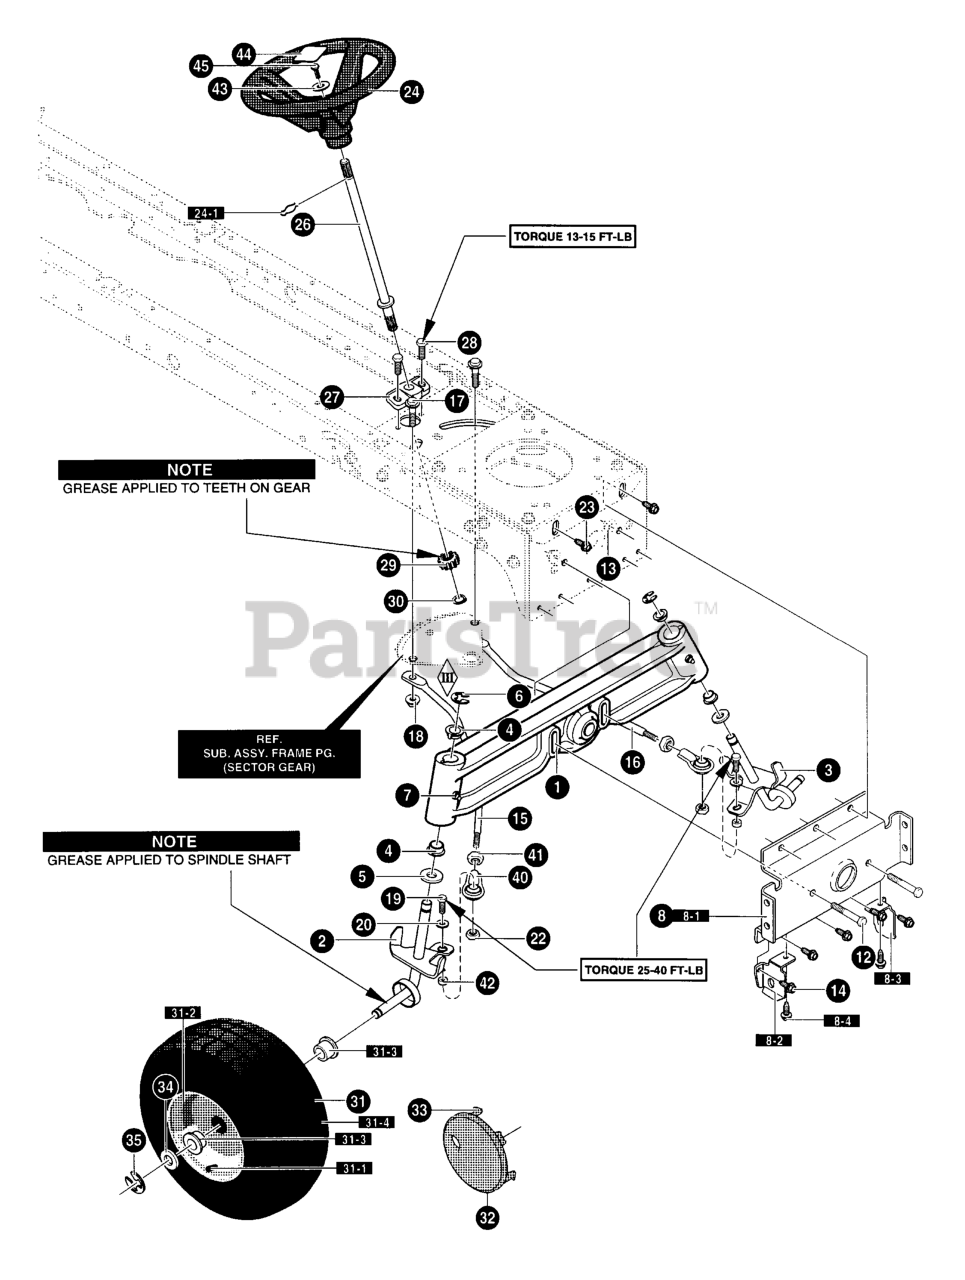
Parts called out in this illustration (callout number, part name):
1	AXLE, FRONT ASSEMBLY
2	SPINDLE, RH
3	SPINDLE, LH
4	BEARING, SPINDLE
6	E- RING
7	ZERK, GREASE FITTING
8	FRONT AXLE/DECK HANGER
8-1	HANGER, AXLE
8-2	HANGER, DECK RH
8-3	HANGER, DECK LH
8-4	SCREW, 5/16-18 x 0.75
12	SCREW, 5/16-24 x 2.75
13	NUT, 5/16- 24
14	SCREW, 5/16-18 x 0.75
15	ROD, DRAG LINK
16	ROD, DRAG LINK
18	NUT, 3/8- 16
20	WASHER, FLAT
22	NUT, 3/8- 16
23	SCREW, 5/16-18 x 0.75
24	STEERING WHEEL
24-1	RETAINER, SPRING
26	SHAFT, STEERING
27	BEARING- LOWER
28	SCREW, 5/16-18 x 0.75
29	GEAR, PINNION
30	RING, RET
31	TIRE & RIM 15X6-6
31-1	VALVE STEM
31-2	RIM, CARLISLE
31-3	BEARING
31-4	TIRE, 15X6X6
32	HUB CAP
33	CLIP, HUB CAP
35	"E" RING
40	TIE ROD
41	NUT 1/2-20
42	SPACER, SLEEVE
43	FLATWASHER
44	INSERT, STEERING WHEEL
